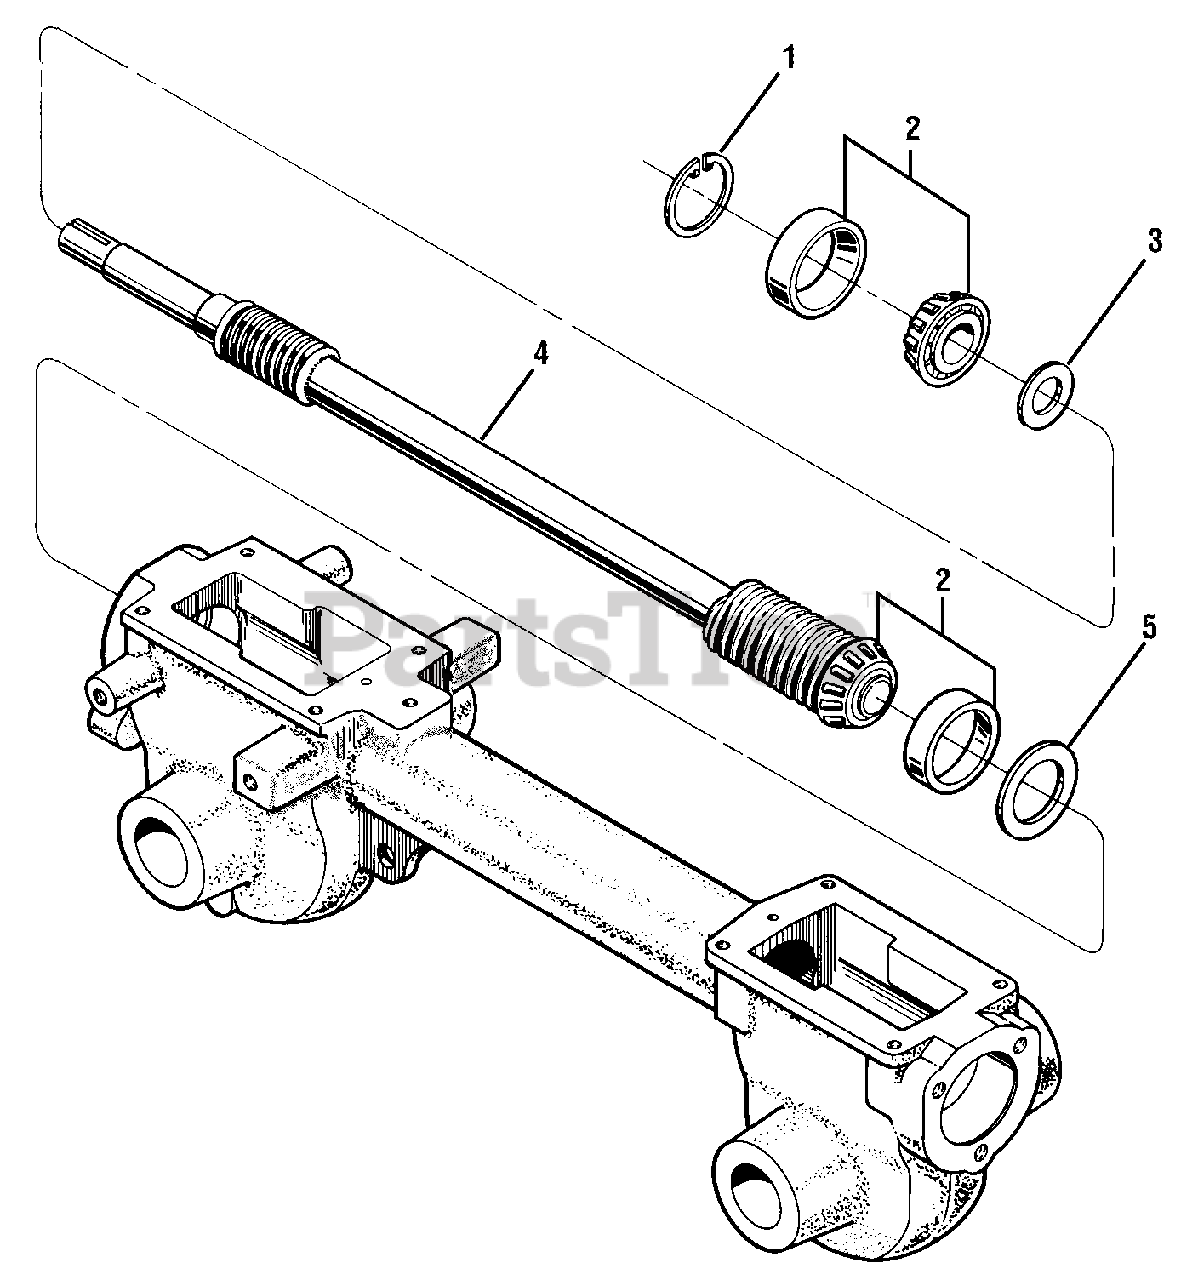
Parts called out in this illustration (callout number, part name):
1	Snap Ring
2	Bearing, Tapered Roller (with race)
3	Support Washer, Rear
4	Drive Shaft (CRT)
5	Shim, Rear Bearing Cap, .010" thick
